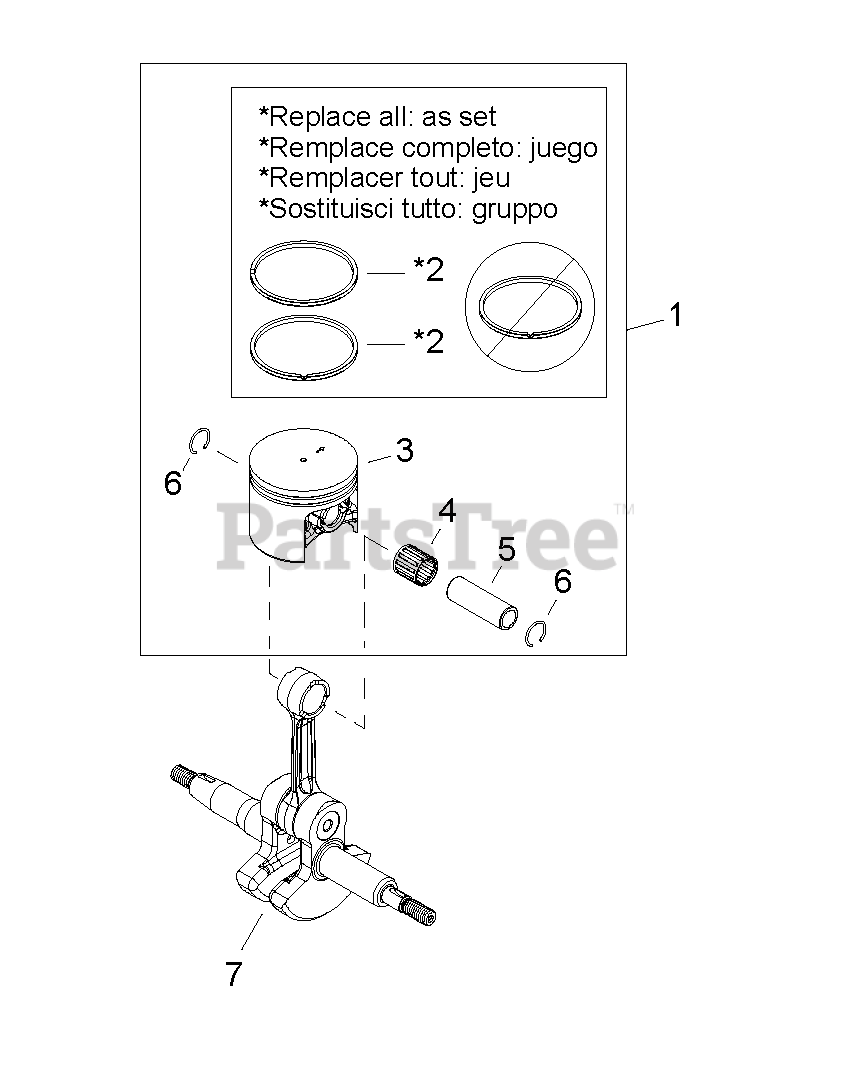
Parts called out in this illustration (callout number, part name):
1	PISTON KIT
2	RING, PISTON
3	PISTON
4	BEARING, NEEDLE
5	PIN, PISTON
6	RING, RETAINING
7	CRANKSHAFT ASSY
